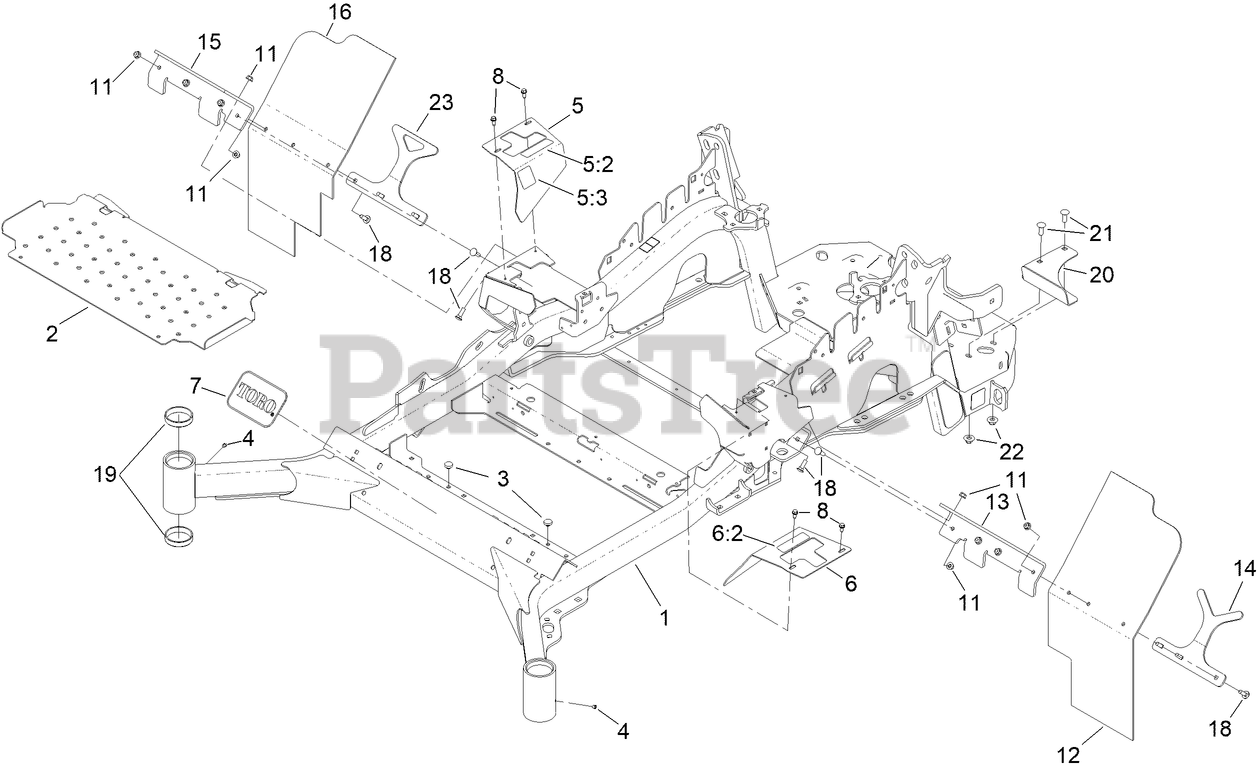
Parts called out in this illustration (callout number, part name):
1	MAINFRAME ASM
2	FLOOR PAN
3	BUMPER
5	RH MOTION CONTROL COVER ASM
5:2	DECAL-CONTROL, MOTION
5:3	DECAL-PARK BRAKE, CE
6	LH MOTION CONTROL COVER ASM
6:2	DECAL-CONTROL, MOTION
7	DECAL
8	SCREW-HWH
11	NUT-HF, NI
12	MUD FLAP
13	BRACKET-MUD FLAP, LH
14	SUPPORT-MUD FLAP, REAR
15	BRACKET-MUD FLAP, RH
16	MUD FLAP
18	BOLT-CARR
19	CUP-BEARING
20	SHIELD-HEAT
21	SCREW-CARR
22	NUT-FLANGE, NI
23	SUPPORT-MUD FLAP RH
